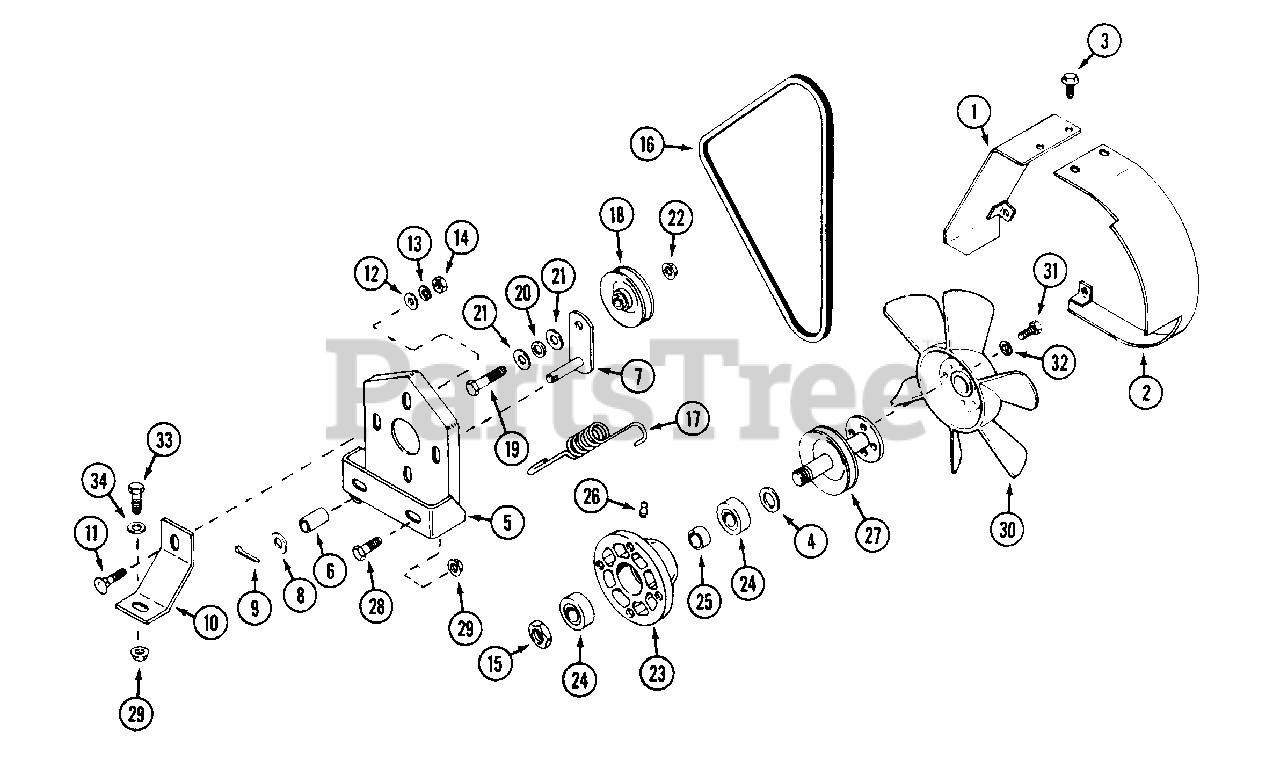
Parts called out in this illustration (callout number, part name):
1	COWLING - fan, rear
2	COWLING - fan, front
3	SCREW - 1/4" - 20 x 1/2" flange
4	WASHER - 3/4" - 1-1/8"
5	BRACKET - fan mounting
6	BUSHING - 1/2"
7	ARM - idler
8	WASHER - 1/2" x 7/8"
9	PIN - cotter 3/32" x 3/4"
10	BRACE - fan mount
11	BOLT - 5/16" - 18 x 1-1/4" carriage
12	WASHER - .344" x .688"
13	LOCKWASHER - 5/16"
14	NUT - 5/16" - 18
15	NUT - 3/4" - 16 lock
16	BELT - 3L x 36"
17	SPRING - tension
18	PULLEY - idler
19	BOLT - 3/8" - 16 x 1-3/4"
20	WASHER - .39" x .625"
21	WASHER - .40" x .81"
22	NUT - 3/8" - 16 flange lock
23	HOUSING ASSEMBLY
24	BEARING - ball 3/4"
25	SPACER - bearing
26	FITTING - 1/4" - 28 lubrication
27	SPINDLE - fan mounting
28	BOLT - 5/16" - 18 x 1-1/4"
29	NUT - 5/16" - 18 flange lock
30	FAN - 11"
31	BOLT - 1/4" - 20 x 1/2"
32	LOCKWASHER - 1/4"
33	BOLT - 5/16" - 18 x 1"
34	WASHER - .375" x .875"
